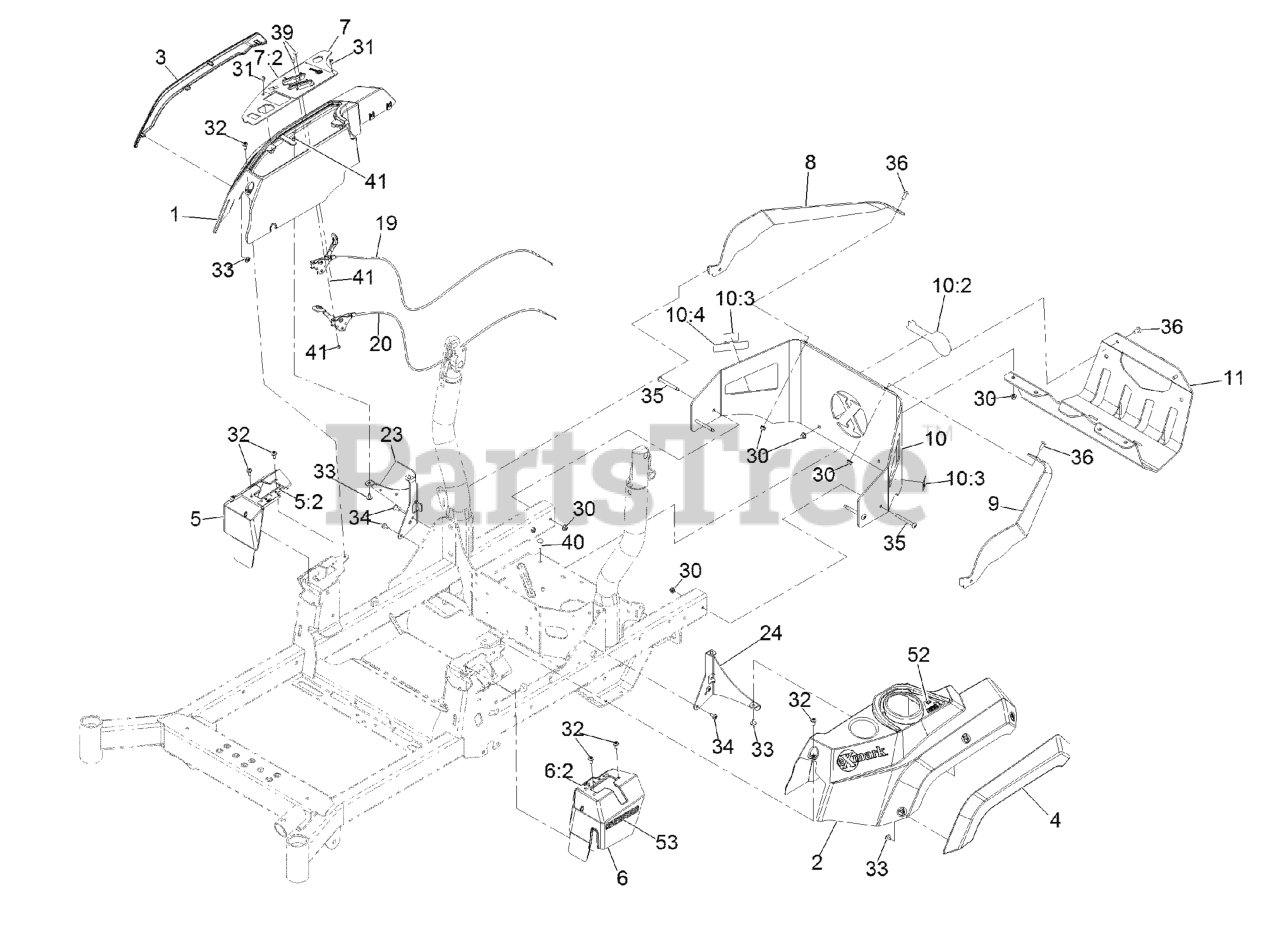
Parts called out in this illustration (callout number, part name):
1	CONSOLE-EXMARK, RH
2	CONSOLE, LH
3	FENDER-RH
4	FENDER-LH
5	COVER-CONTROL, MOTION (RH
5:2	Decal-Control, Motion (RH)
6	COVER-CONTROL, MOTION (LH
6:2	Decal-Control, Motion (LH)
7	CTRL PANEL ASM W/DECAL
7:2	DECAL-CONTROL PANEL
8	SUPPORT-UPPER, RH
9	SUPPORT-UPPER, LH
10	REAR GUARD ASM
10:2	DECAL-EXMARK LOGO
10:3	DECAL-WARNING
10:4	DECAL-ARRESTOR, SPARK
11	GUARD-MUFFLER
19	CABLE-CONTROL, CHOKE
20	CABLE-CONTROL, THROTTLE
23	SUPPORT-CONSOLE, RH
24	BRACKET-CONSOLE, LH
30	NUT-HF, NI
31	SCREW-HWH
32	SCREW-SHOULDER
33	SCREW-TORX
34	SCREW-TORX
35	SCREW-TORX
36	SCREW-TORX
39	BOLT-CARR
40	SCREW-CARR
41	NUT-LOCK, NI
52	DECAL-FILL, FUEL
53	DECAL-S-SERIES
